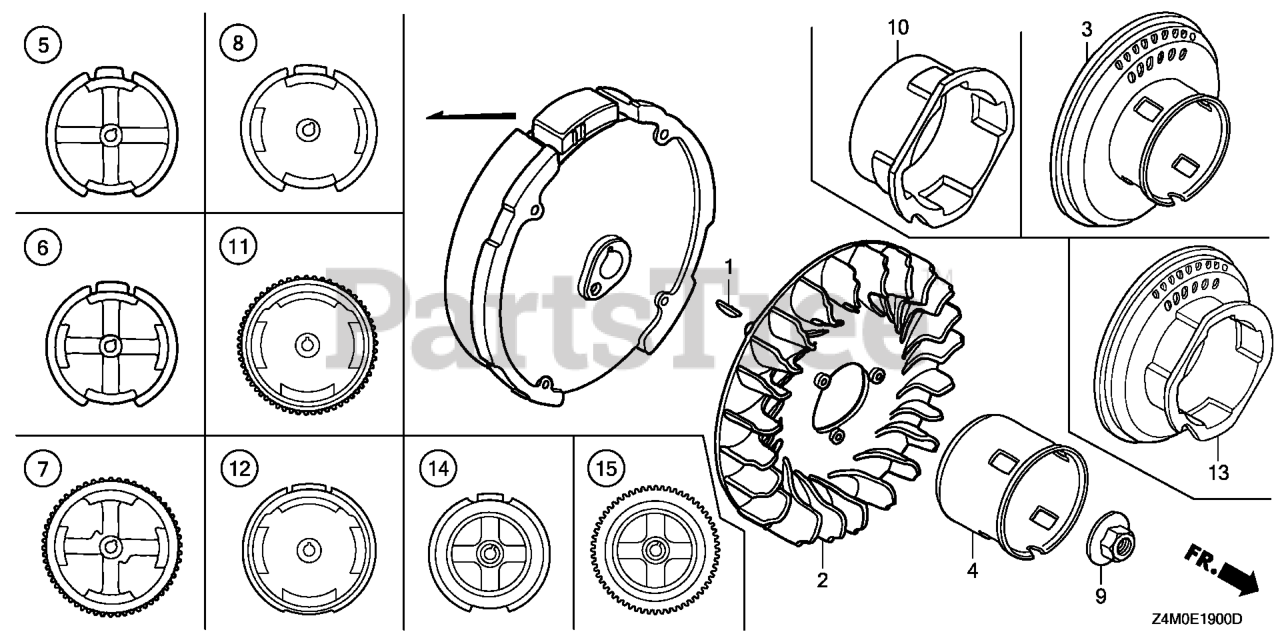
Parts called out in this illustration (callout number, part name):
1	KEY, SPECIAL WOODRUFF (25X18)
2	FAN, COOLING
4	PULLEY, STARTER
6	FLYWHEEL (LAMP)
9	NUT, SPECIAL (14MM)
10	PULLEY, STARTER
